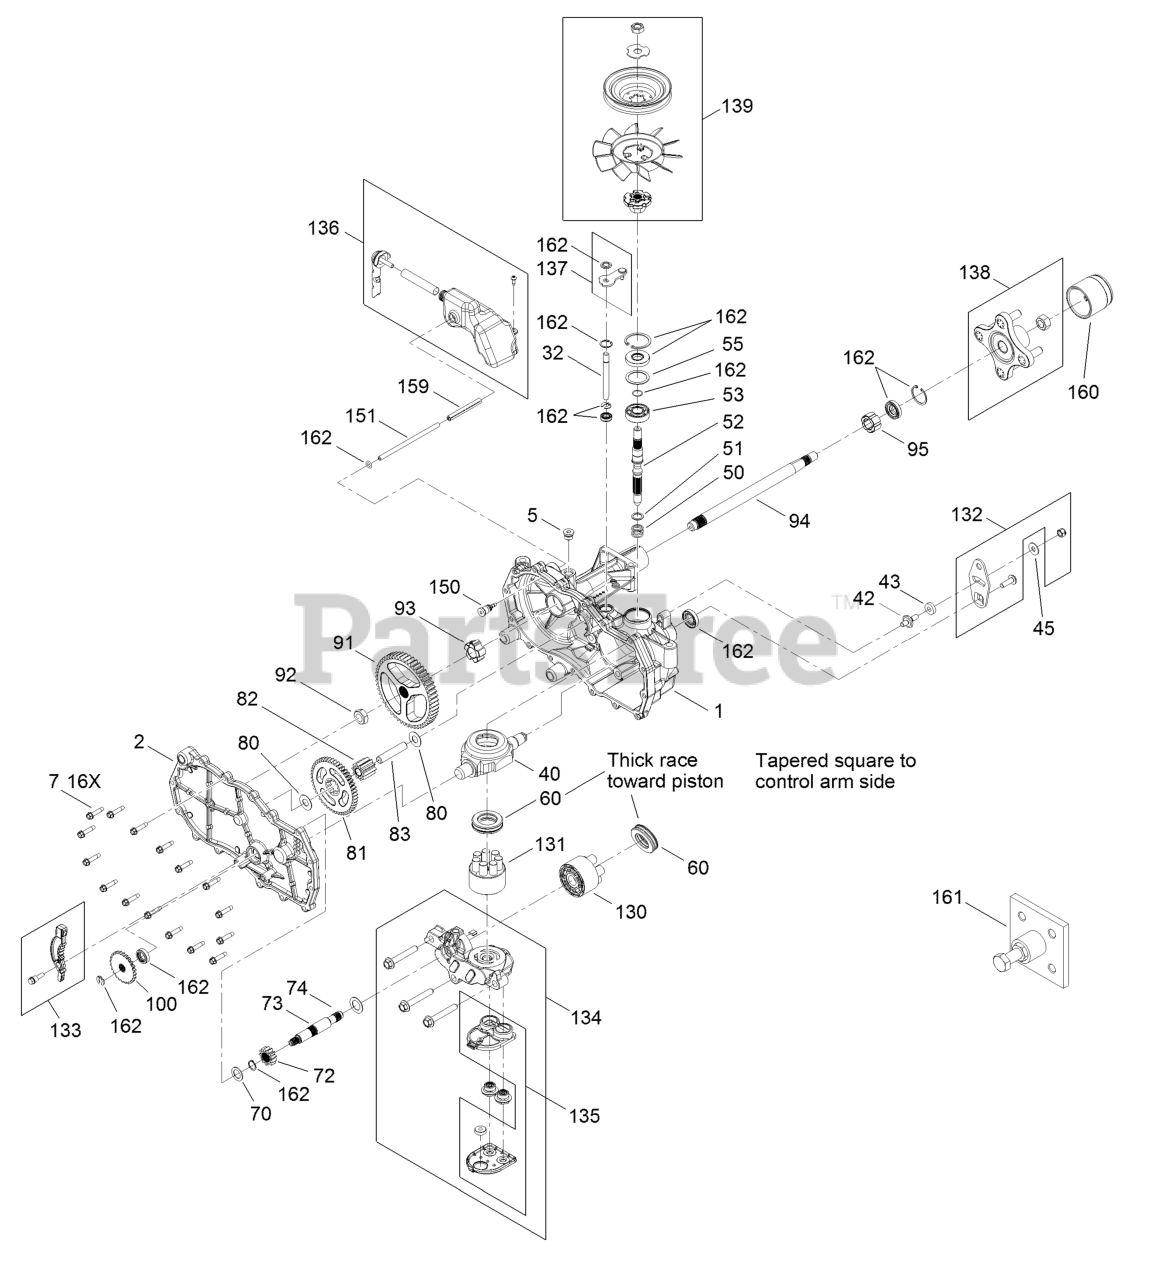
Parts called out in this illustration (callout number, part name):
1	MAIN HOUSING ASM
2	HOUSING SIDE KIT
5	PLUG-THREAD, STRAIGHT
7	SCREW-HHF
32	ROD-BYPASS
40	SWASHPLATE-TRUNNION
43	PUCK-FRICTION
52	SHAFT-INPUT
53	BEARING-BALL
60	BEARING-THRUST
70	WASHER-FLAT
72	GEAR-PINNION, 13T
73	SHAFT-MOTOR
80	Washer
81	GEAR-10T/48T
82	GEAR-JACKSHAFT, 10T
83	PIN-JACKSHAFT
91	GEAR-BULL
93	BUSHING-INBOARD
94	SHAFT-AXLE
95	BEARING-SLEEVE
100	DISC-BRAKE, COG
130	CYLINDER BLOCK KIT
131	PUMP BLOCK ASM
132	CONTROL ARM KIT
133	BRAKE ARM KIT
134	CENTER SECTION FILTER KIT
135	FILTER KIT
136	LH EXPANSION TANK KIT
137	BYPASS ARM KIT
138	HUB KIT
139	FAN PULLEY KIT
150	FITTING-SAE
159	CASE-TUBE
160	CAP-AXLE
162	SEAL AND RING KIT
